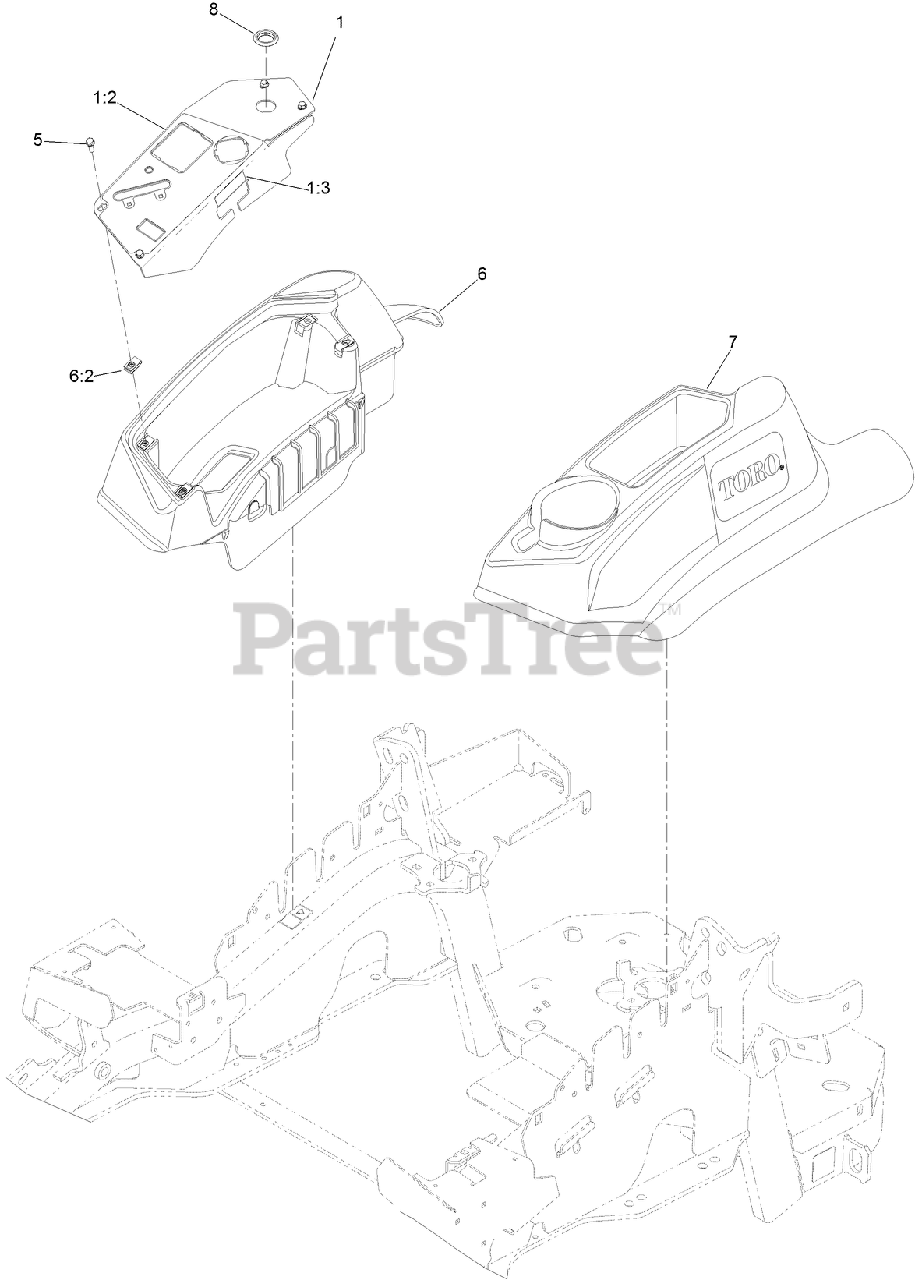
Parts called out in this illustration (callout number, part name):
1	CONTROL PANEL W/DECAL ASM
1:2	DECAL-PANEL, CONTROL
1:3	DECAL-FUSES
5	SCREW-HWH
6	RH CONSOLE ASM
7	CONSOLE-LH
8	PLUG-PLASTIC
